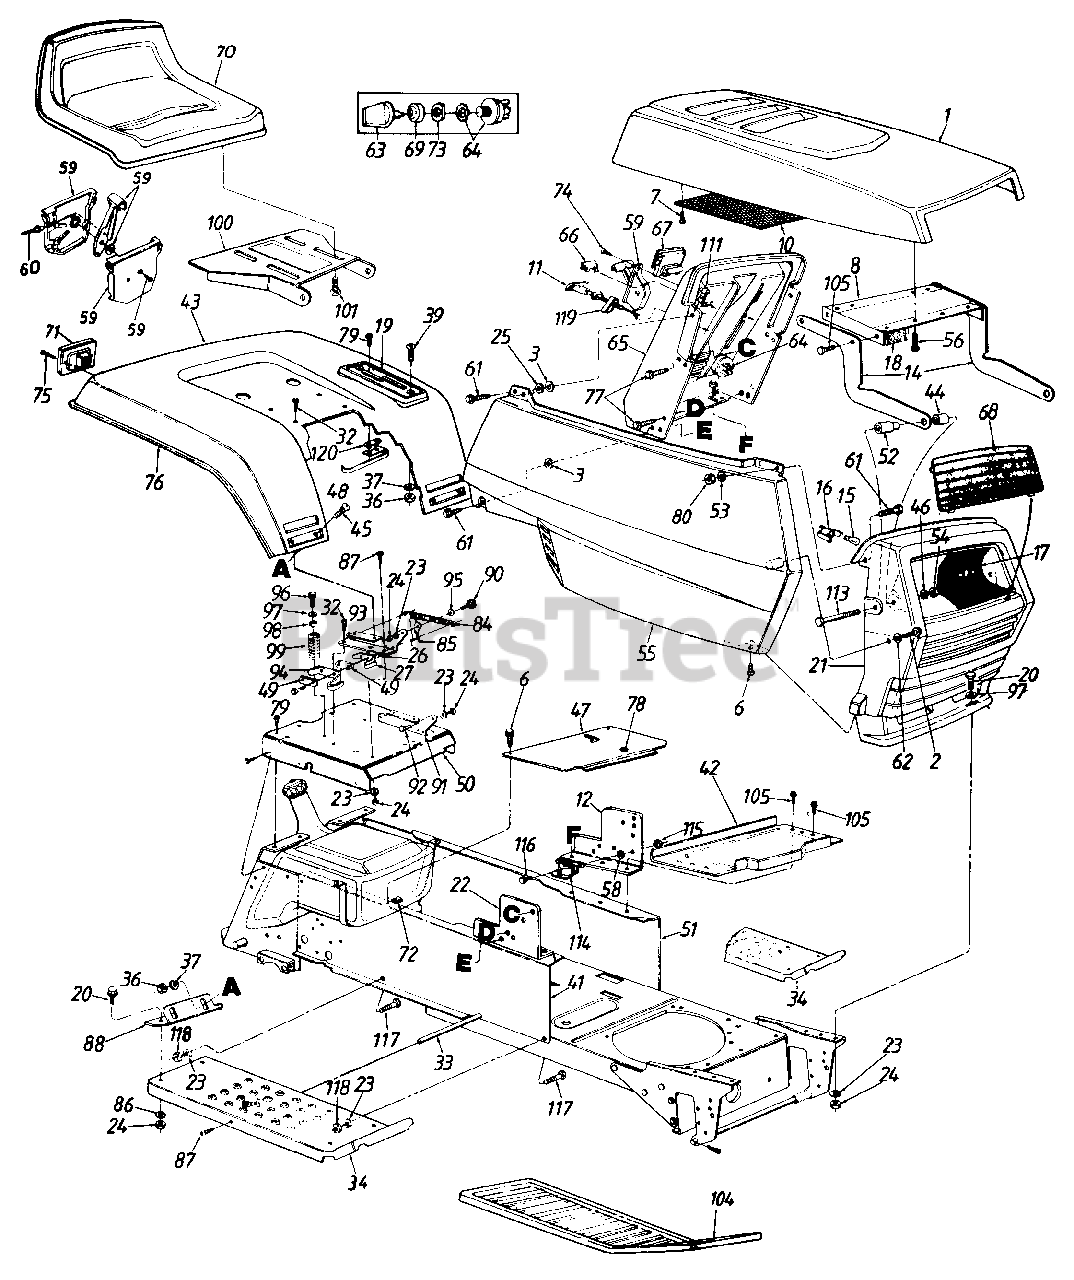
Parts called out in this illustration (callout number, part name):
3	Bolt Retainer 1/4" I.D.
6	Truss Mach. B-Tap Scr. #10 x .5" Lg.
7	Hex Wash Hd. AB-Tap Scr. #8 x .5" Lg.
8	Hood Plate
11	Choke Control
12	Dash Support Brkt.-L.H.
14	Hood Hinge
15	Lamp
16	Twist Lock-Lamp Socket
17	Reflector-Headlight
19	Speed Control Index Brkt.
20	Hex Bolt 5/16-18 x 1.0" Lg.
21	Grille
22	Dash Support Bracket-R.H.
23	L-Wash. 5/16" I.D.
24	Hex Nut 5/16-18 Thd.
25	Fl-Wash. 1/4" I.D. x .93" O.D.
26	Insulator Boss Plate
27	Seat Spring Switch
32	Hex Wash. Hd. AB-Tap Scr. 5/16 x .75" Lg.
33	Running Board Rod
37	L-Wash. 1/4" I.D.
39	Truss Mach. Scr. 1/4-20 x 1.0" Lg.
41	R.H Side Frame
42	Battery Plate
45	Carriage Bolt 1/4-20 x .50" Lg.
46	Fl-Wash. .328n l.D. x .68" O.D.
47	Transmission Panel
48	Reverse Safety Switch
49	Insulator Plate
50	Seat Plate
53	Fl-Wash. .281" I.D. x .5" O.D.
54	Hex Cent. L-Nut 5/16-18 Thd.
55	Side Cover-R.H.
56	Hex Wash. Hd. B-Tap Scr. 1/4 x .62" Lg.
58	Ext. L-Wash. 1/4n l.D.
59	Throttle Control Box Ass'y.
60	Throttle Control Wire 35" Lg.
61	Hex Bolt 1/4-20 x .62" Lg.
62	Fl-Wash. .281" I.D. x .73" O.D.
64	Ignition Switch
66	Light Switch
67	Ammeter
68	Lens
69	Ignition Switch Cap
71	Taillight Ass'y.
72	Speed Nut #10Z
73	Ignition Switch Nut
74	Truss Mach. AB-Tap Scr. #10 x .5n Lg.
75	Truss Hd. AB-Tap Scr. #6 x .62" Lg.
77	Hex Wash. Hd. Tap Scr. 1/4 x.75n Lg.
78	Snap Bushing
79	Hex Wash. Hd. AB-Tap Scr. #8 x .50" Lg.
80	Hex L-Nut 1/4-20 Thd.
84	Ext. Spring 5.31n Lg.
85	Seat Lift Brkt.
86	Bell-Wash. .345n l.D. x .88" O.D.
87	Truss Machine Scr. 5/16-18 x 75" Lg
95	Spr.-Wash..445n l.D.
96	Hex Wash. Hd. Tap Scr. 5/16-18 x .75" Lg.
97	Fl-Wash. .344n l.D.
99	Compression Spring
100	Seat Pivot Bracket
101	Hex Tap Scr. 3/8-16 x .75"
105	Hex Tap Scr. 1/4-20 x .5" Lg.
111	Speed Nut 1/4-20 Thd.
113	Hex Bolt 5/16-18 x 2.75"
114	Solenoid
115	Hex Sems Nut 1/4-20 Thd.
116	Hex Bolt 1/4-20 x .5" Lg.
117	Rib Neck Bolt 5/16-24 x .75n Lg.
118	Hex Nut 5/16-24 Thd.
119	Retainer Clip
120	Insulator Nut Plate
